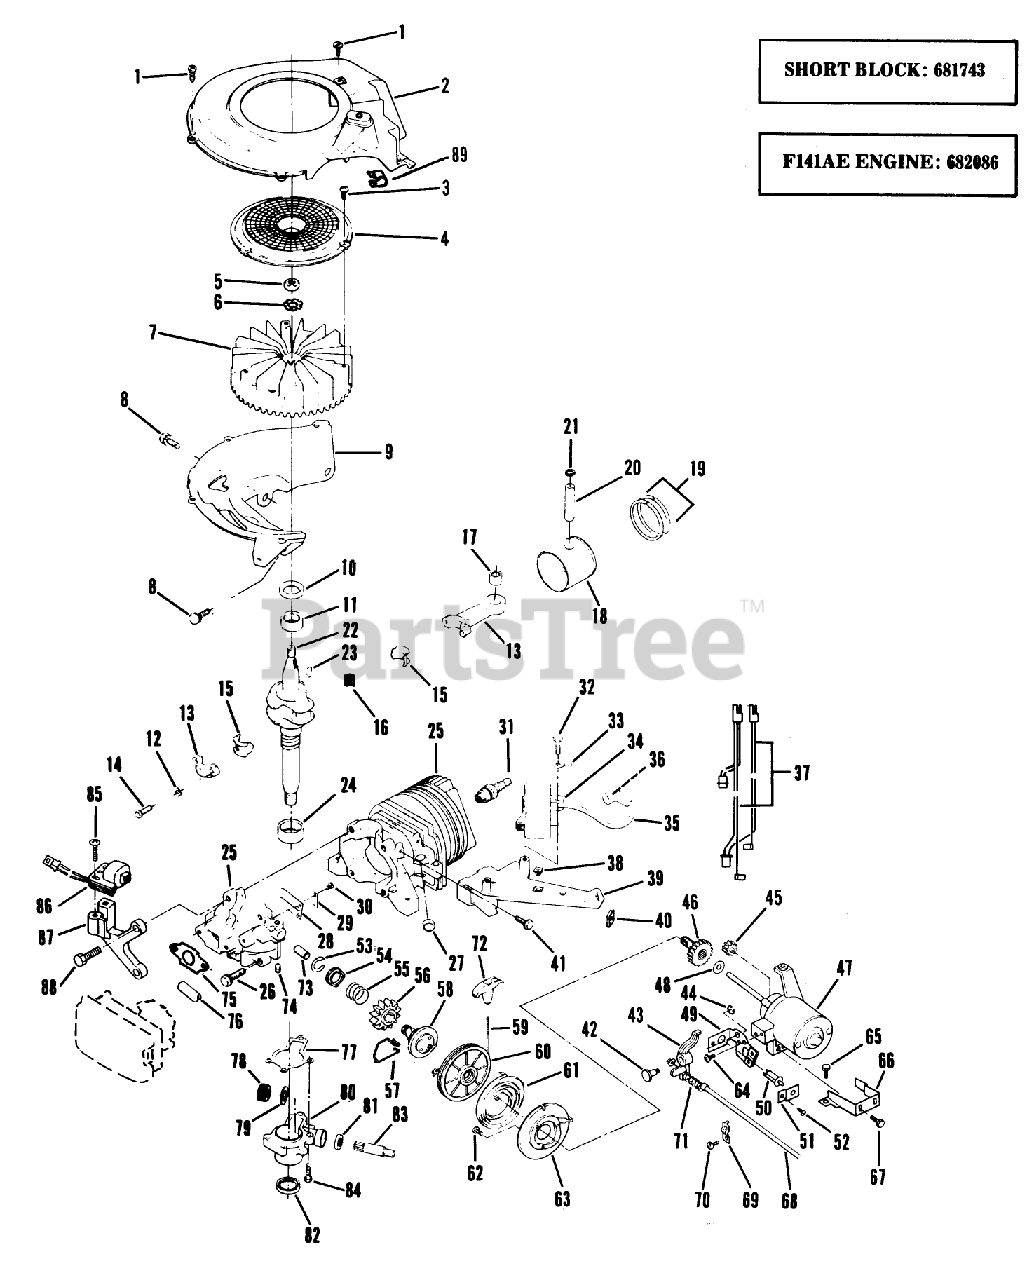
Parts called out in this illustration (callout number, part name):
1	SCREW S
2	AIR BAF&EYELET S
3	SCREW F
8	SCREW-SEMS
11	BEARING V
15	LINER ASM
17	BEARING AY F
21	RING-RETAINING
24	BEARING S
26	SCREW S
27	PLUG-CORE VF
29	PLATE-BACKUP, REED
33	TERMINAL S
35	HT LEAD&COVER XEV
38	NUT-CLIP
40	NUT - SPEED S
42	PIN INTERLOCK
53	RET.RING EF
55	*SPRING PINION EF
56	PINION EF
57	SPRING F
58	CLUTCH AY S
60	PULLEY & CLUTCH BEARING
61	SPRING S
62	SCREW EF
72	HANDLE STARTER S
73	SLEEVE F
74	SET SCREW
75	GASKET CARB S
77	GASKET S
78	GEAR, DR SHAFT S
79	THRUST WASHER
89	Clamp-Wire Harness
